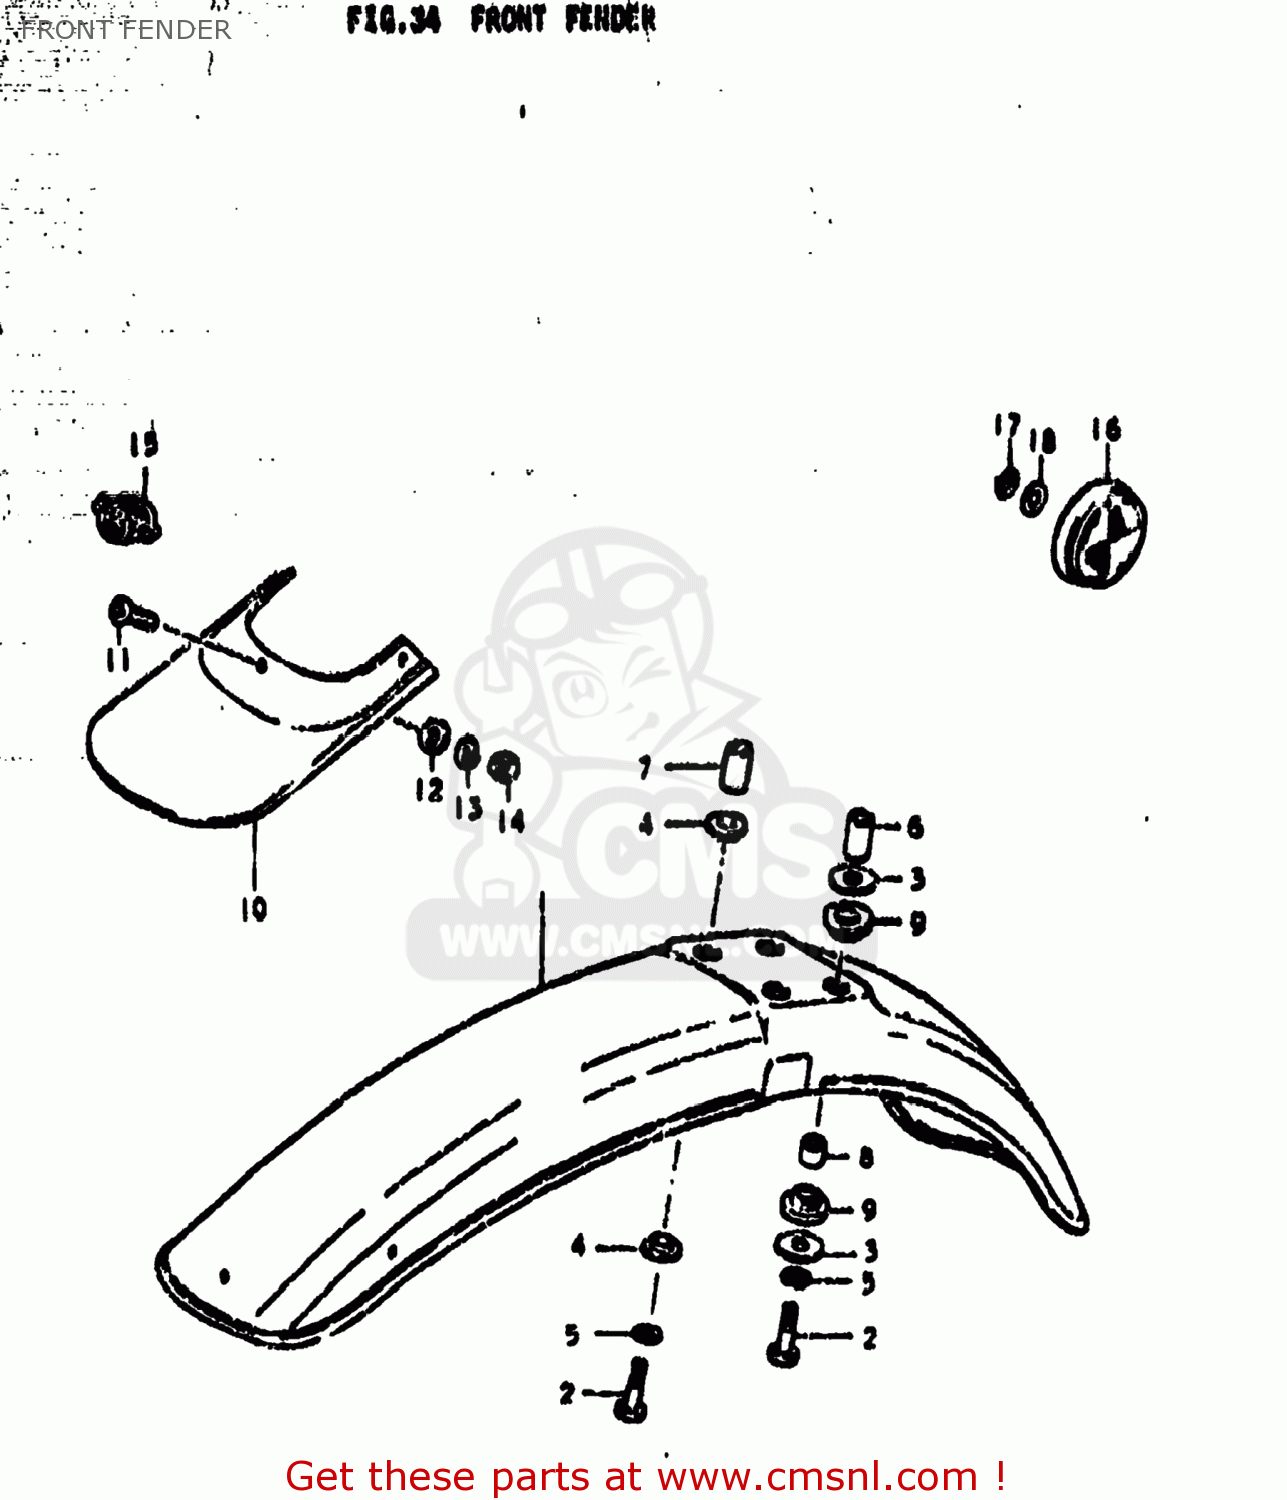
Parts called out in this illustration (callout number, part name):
1	FENDER,FRONT
2	BOLT
4	WASHER (6.5X20X1.2)
5	LOCK WASHER
6	SPACER
7	SPACER
8	SPACER (6.8X10X10)
9	CUSHION
10	MUD FLAP,FRONT FENDER
11	SCREW
12	WASHER
13	LOCK WASHER
14	NUT
16	REFLEX REFLECTOR,FR
17	LOCK WASHER
18	WASHER
